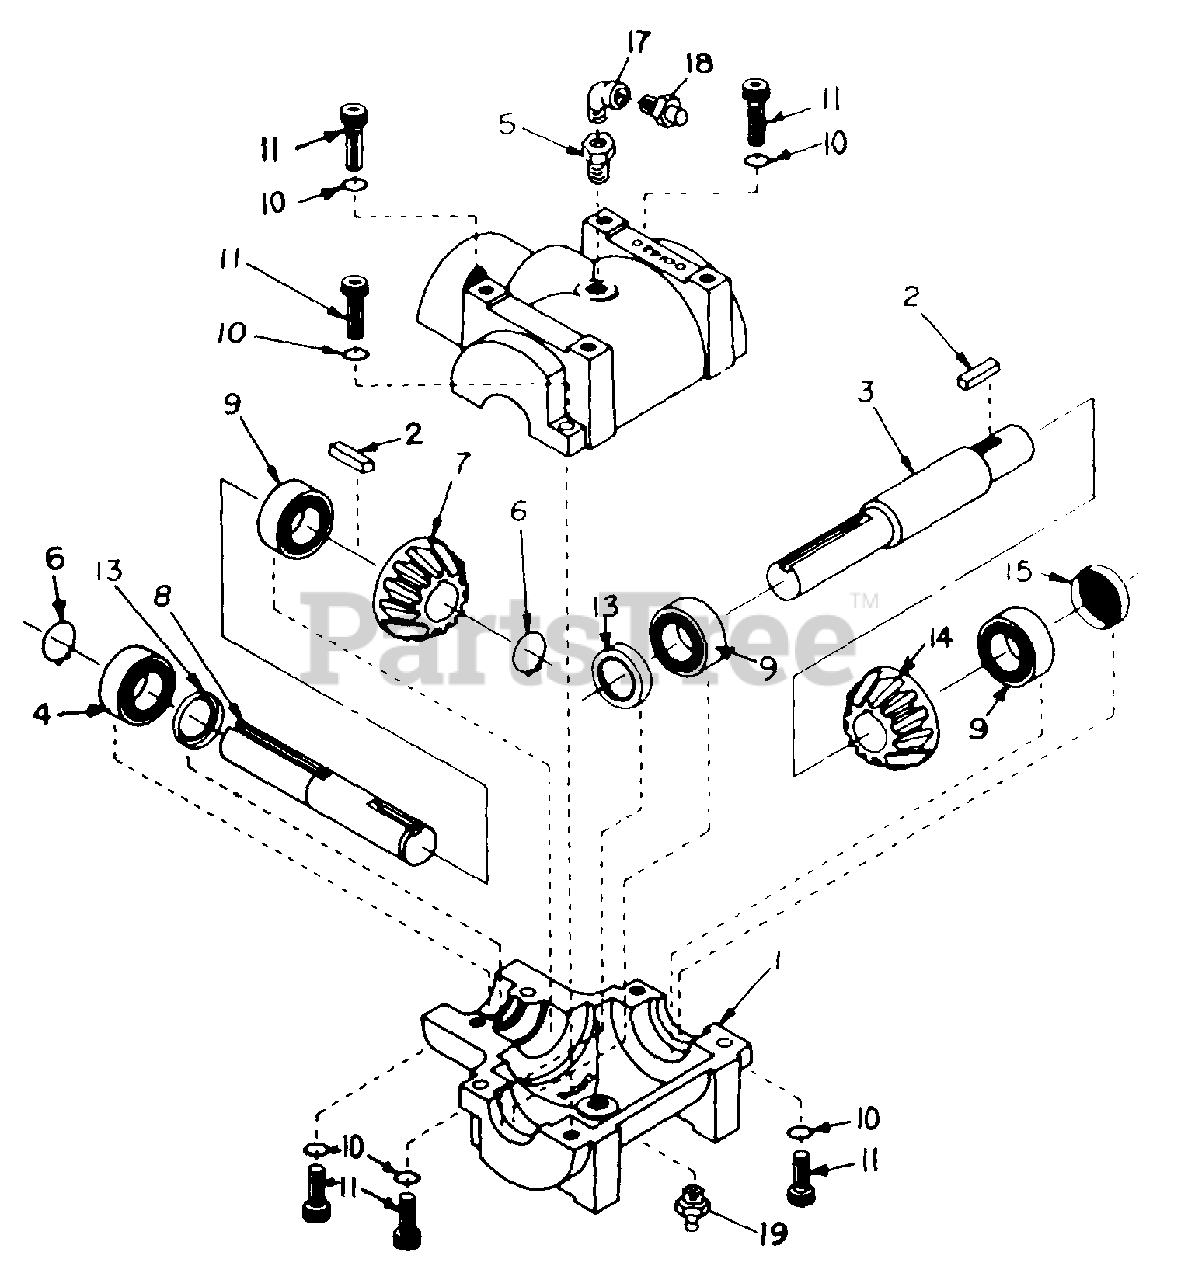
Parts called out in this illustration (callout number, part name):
2	Key, 3/16" x 3/16" x 1"
4	Ball Bearing
5	Pipe Bushing, 1/4" x 1/8"
6	Retaining Ring
7	Output Shaft Gear
9	Ball Bearing
10	Lockwasher
11	Allenhead Capscrew
14	Input Shaft Gear
15	Expansion Plug
17	Street Elbow, 1/8" x 90°
19	Grease Zerk, 1/4" NPT
